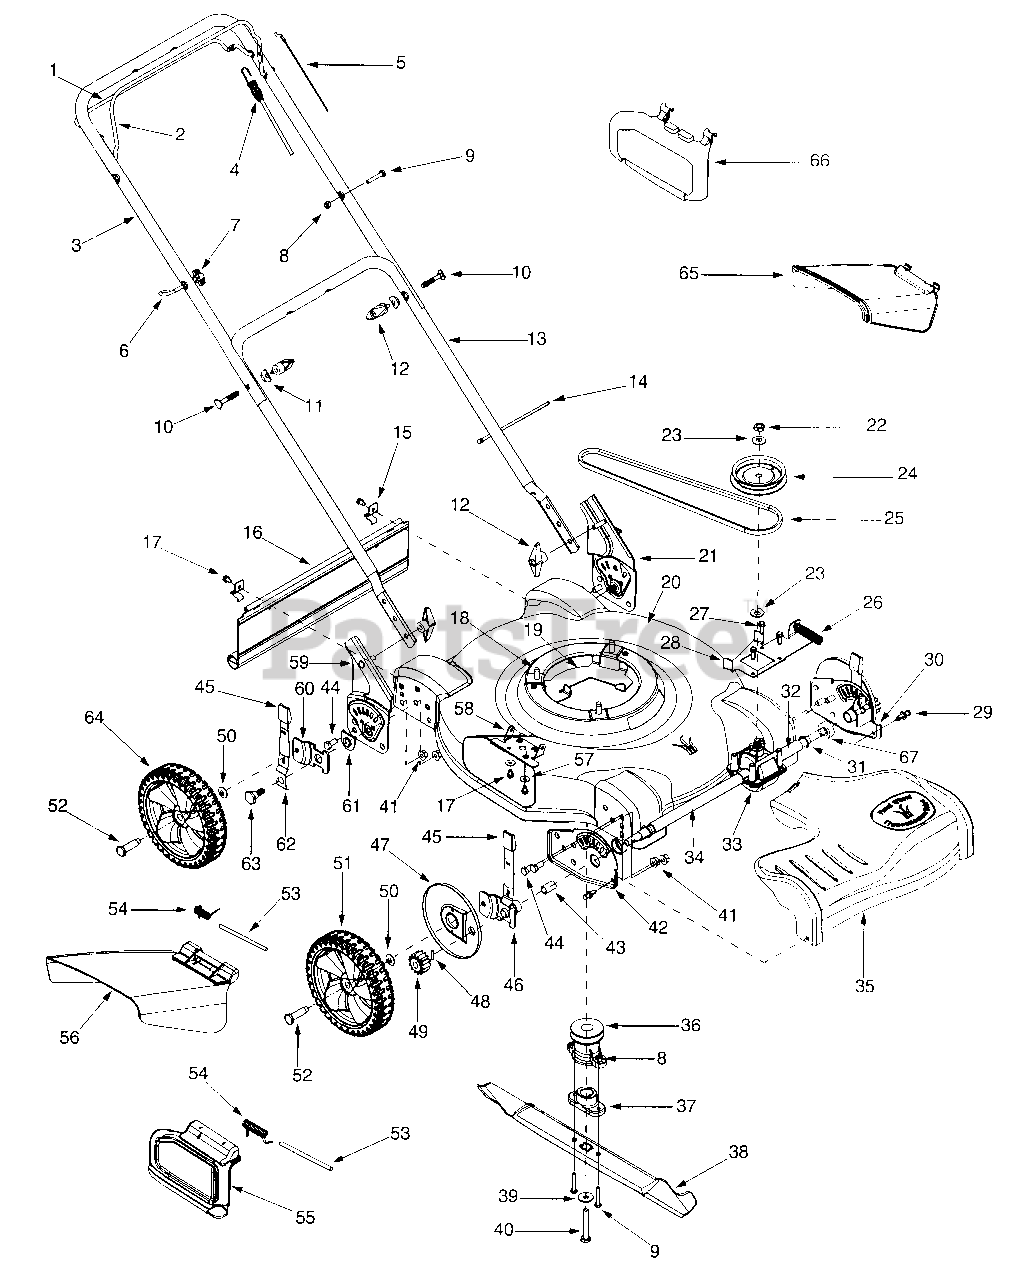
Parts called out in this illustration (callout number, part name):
1	Drive Control Handle
2	Blade Control Handle
4	Drive Control Cable
5	Blade Control Cable - B&S
5	Blade Control Cable - Tec
6	Eye Bolt
7	Wing Nut 1/4-20
8	Hex Lock Nut 1/4-20
9	Hex Cap Screw 1/4-20x 1.5
10	Carriage Bolt 5/16-18 x 2.0
11	Shoulder Washer .320 ID x .93 OD
12	Wing Nut 5/16-18
14	Cable Tie
15	Hinge Clip
16	Trail Shield
17	Hex Screw 1/4-14 x .625
18	Hex Washer Screw 3/8-16 x 1.875
19	Engine Belt Keeper Bracket
22	Jam Nut 7/16-20
23	Bell Washer .45 ID x 1.00 OD
24	Pulley
25	V-Belt
26	Compression Spring
27	Hex Washer Screw 1/4-20 x.750
28	Transmission Belt Keeper Bracket
29	Rivet
31	Retainer Ring
32	Sleeve Spacer, .550 ID x 2.5
33	Transmission Assembly
34	Sleeve Spacer .550 ID x 8.9
35	Transmission Cover
36	Drive Pulley
37	Blade Adapter
38	Blade 22"
38	Mulching Blade 22"
39	Bell Washer .396 ID x 1.140 OD
40	Hex Cap Screw 3/8-24 x 2.5
41	Lock Nut 3/8-16
43	Sleeve Bearing
44	Hex Cap Screw 3/8-16 x .75
45	Adjustment Knob
46	Spring Lever Assembly
47	Wheel Dust Cover
48	Pin
49	Spur Gear 14T - LH
49	Spur Gear 14T - RH
50	Bell Washer .401 ID x .870 OD
51	Wheel Assembly 8 x 1.8
52	Shoulder Screw 3/8-16
53	Hinge Pin
54	Torsion Spring - Side Discharge
54	Torsion Spring - Mulching Baffle
55	Mulching Baffle
56	Side Discharge Assembly
57	Bell Washer .265 ID x .75 OD
58	Chute Hinge
61	Height Adjustment Bearing
62	Spring Lever
63	Shoulder Screw 3/8-16
64	Wheel 8 x 1.8
65	Snap Discharge Chute
66	Snap Mulching Plug
67	Bearing Spacer
